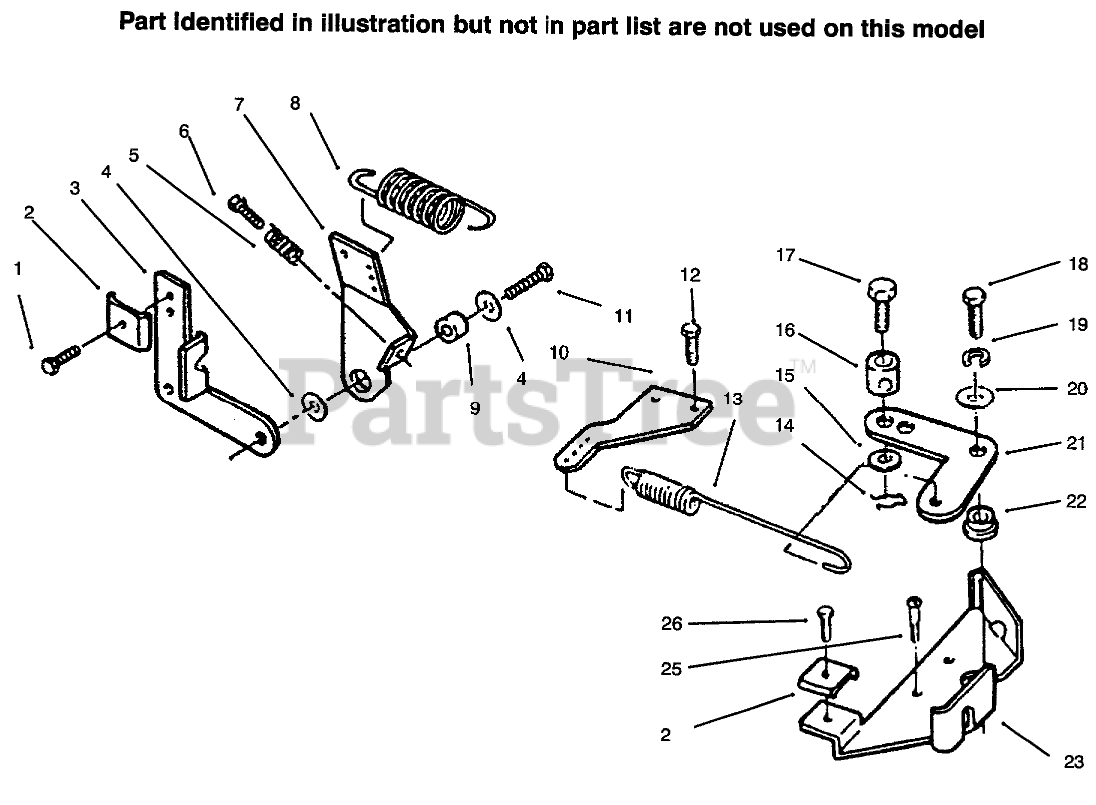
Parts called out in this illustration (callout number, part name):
1	SCREW-TAPPING
3	BRACKET
4	WASHER-FLAT
5	SPRING
6	SCREW-TAP
7	GOVERNOR CONTROL ARM
8	SPRING
9	BUSHING
10	ADAPTER-GOV ARM
11	SCREW-HWH
12	Screw
13	SPRING-GOV
14	PIN-COTTER
15	WASHER-FLAT
16	BUSHING
17	SCREW
18	SCREW - CAP HEX HEAD
19	WASHER-LOCK, SPRING
20	WASHER-FLAT
21	Governor Control Arm
22	BUSHING-GOV CONTROL
23	Bracket-Governor Cont
25	HEX HD CAP SCREW
26	TAPPING HEX HD CS
